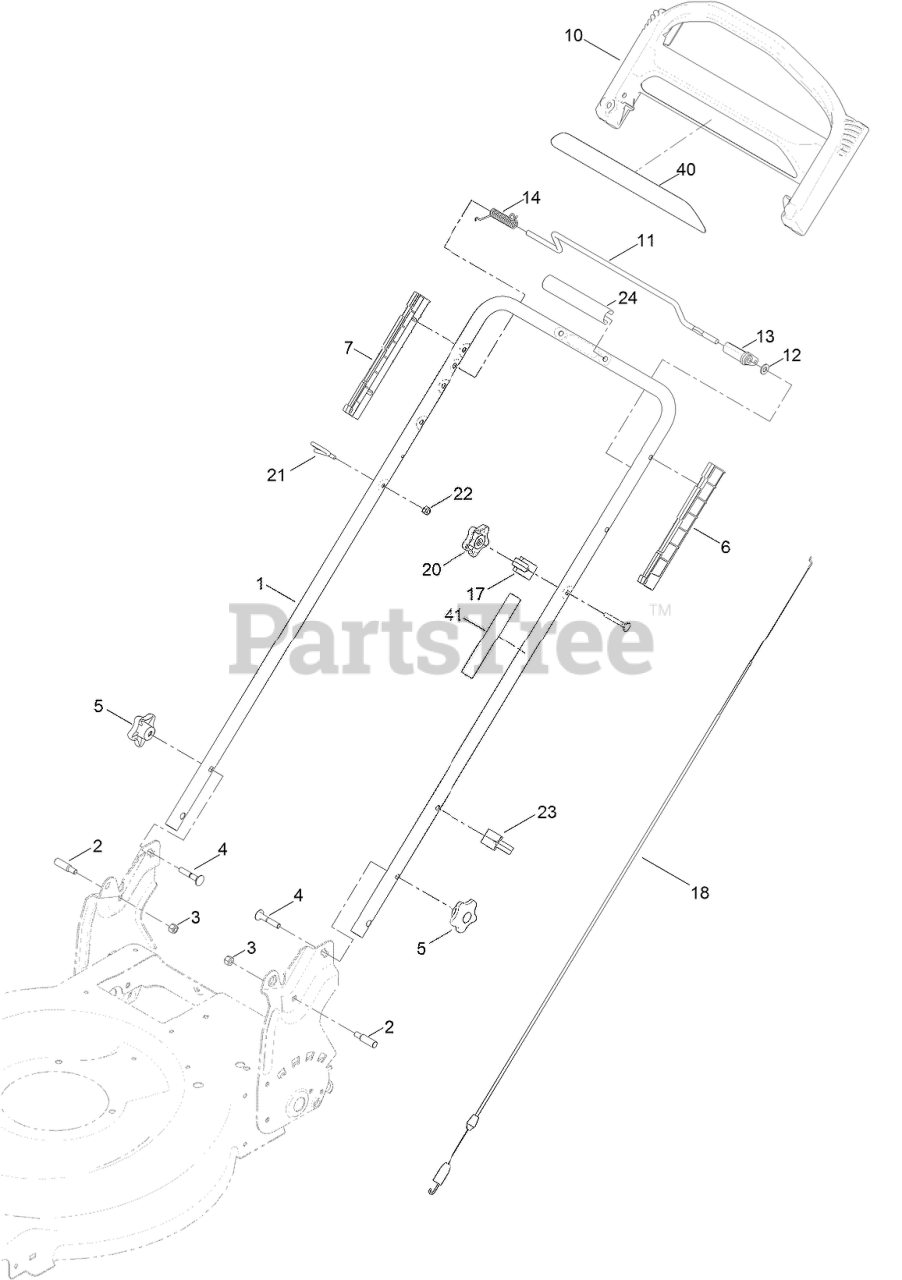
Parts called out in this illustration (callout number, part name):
2	BOLT-SHOULDER
3	NUT-LOCK, NI
4	SCREW-CARR
5	KNOB-HANDLE
6	GUIDE-LH
7	GUIDE-RH
10	HANDLE-CONTROL
11	BAR-CONTROL, TRACTION
12	WASHER-PLAIN
13	LEVER-TRACTION
14	Spring-Torsion
17	ANCHOR-CABLE
18	CABLE-TRACTION
20	KNOB-HANDLE, LOCKING
21	GUIDE-ROPE
22	NUT-LOCK, NI
23	GUIDE-CABLE
24	HANDLE-COVER
41	DECAL-TRACTION, ADJUST
